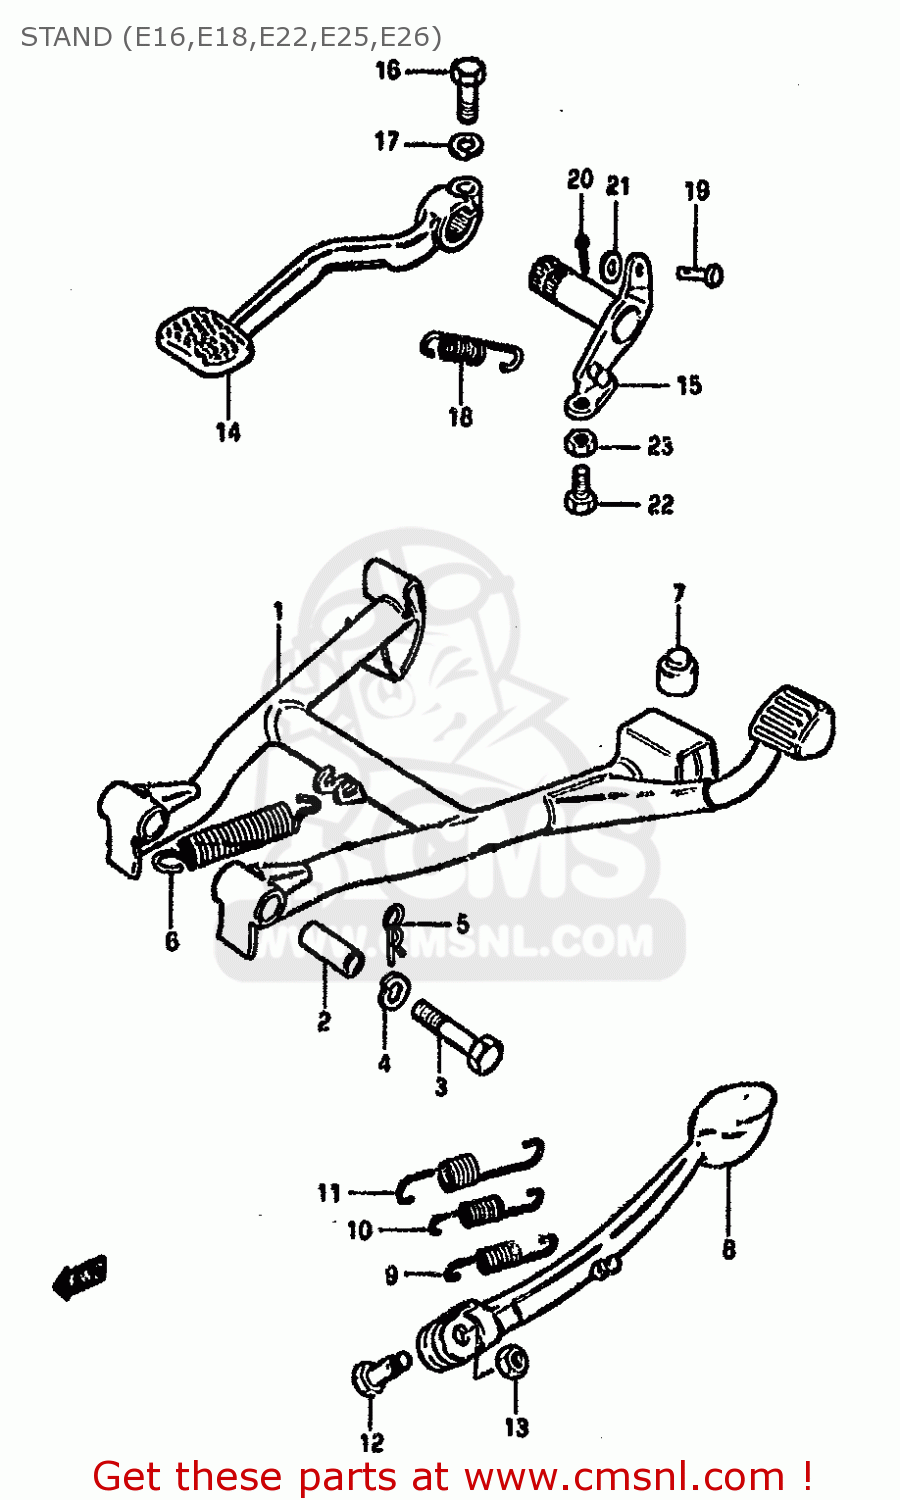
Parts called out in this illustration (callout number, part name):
1	STAND,CENTER
2	SPACER(10X16X38.8)
3	BOLT
4	LOCK WASHER
5	CLIP
6	SPRING
7	CUSHION
8	STAND, PROP
9	SPRING
10	SPRING
11	SPRING
12	BOLT(10X32)
13	NUT
14	PEDAL, BRAKE
15	ARM,BRAKE PEDAL
16	BOLT
17	LOCK WASHER
18	SPRING
19	PIN
20	PIN
21	WASHER
22	BOLT
23	NUT
